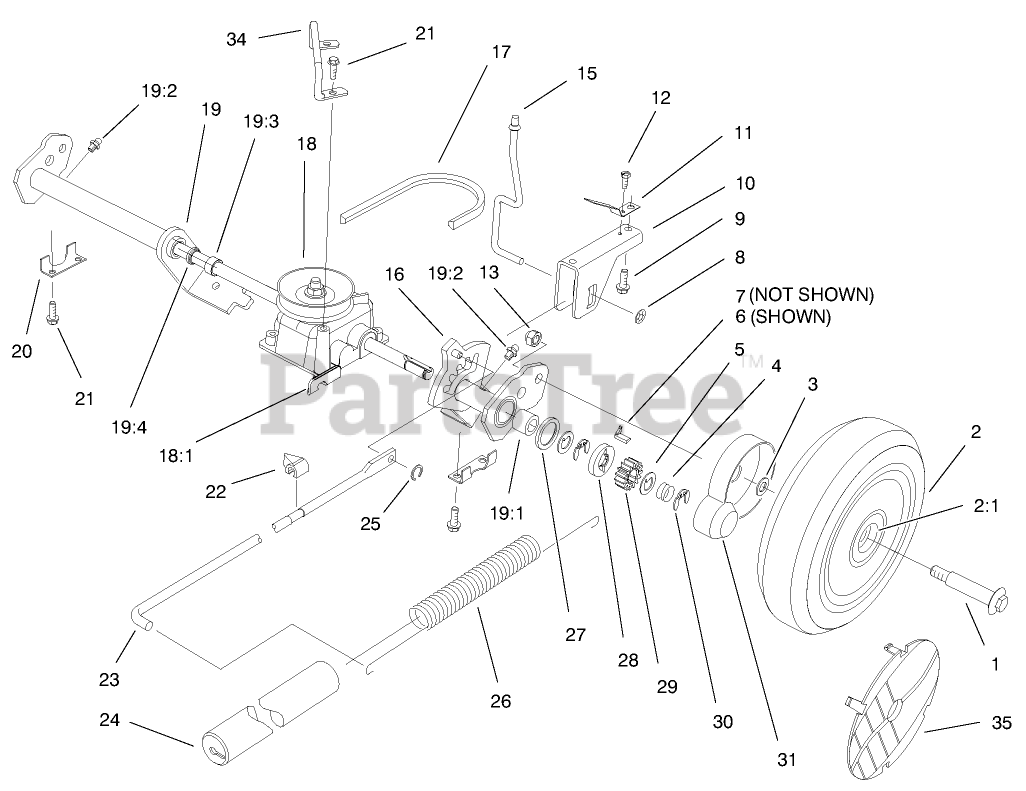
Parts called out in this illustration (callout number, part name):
1	BOLT-WHEEL
2	WHL & TIRE ASSEMBLY
2:1	BUSHING
3	SPACER-COVER, WHEEL
4	SPRING-COMPRESSION
5	WASHER-THRUST, KEYED
6	KEY-ROCKING, LH
7	KEY-ROCKING, RH
8	PUSHNUT
9	SCREW
10	SADDLE - HOC
11	SPRING - TRIGGER RET
12	SCREW 8 - 32 X 250
13	NUT-HEX
15	TRIGGER ROD
16	ASM - LH PIVOT ARM
17	V-BELT
18	GEAR CASE ASSY
18:1	TRACTION BRACKET
19	ASM - RH PIVOT ARM
19:1	BEARING-ROLLER
19:2	FITTING-GREASE
19:3	BUSHING
19:4	SEAL-OIL
20	REAR SECURING PLATE
21	SCREW-HWH
22	INDICATOR-HEIGHT OF CUT
23	LINK ROD
24	COVER-SPRING
25	GRIP RING
26	SPRING-COUNTERBALANCE
27	RING-FRICTION
28	WASHER-CLUTCH
29	GEAR-PINION
30	RING-CLIP, LOCKING
31	COVER-WHEEL
34	Retainer Belt
35	COVER-WHEEL
